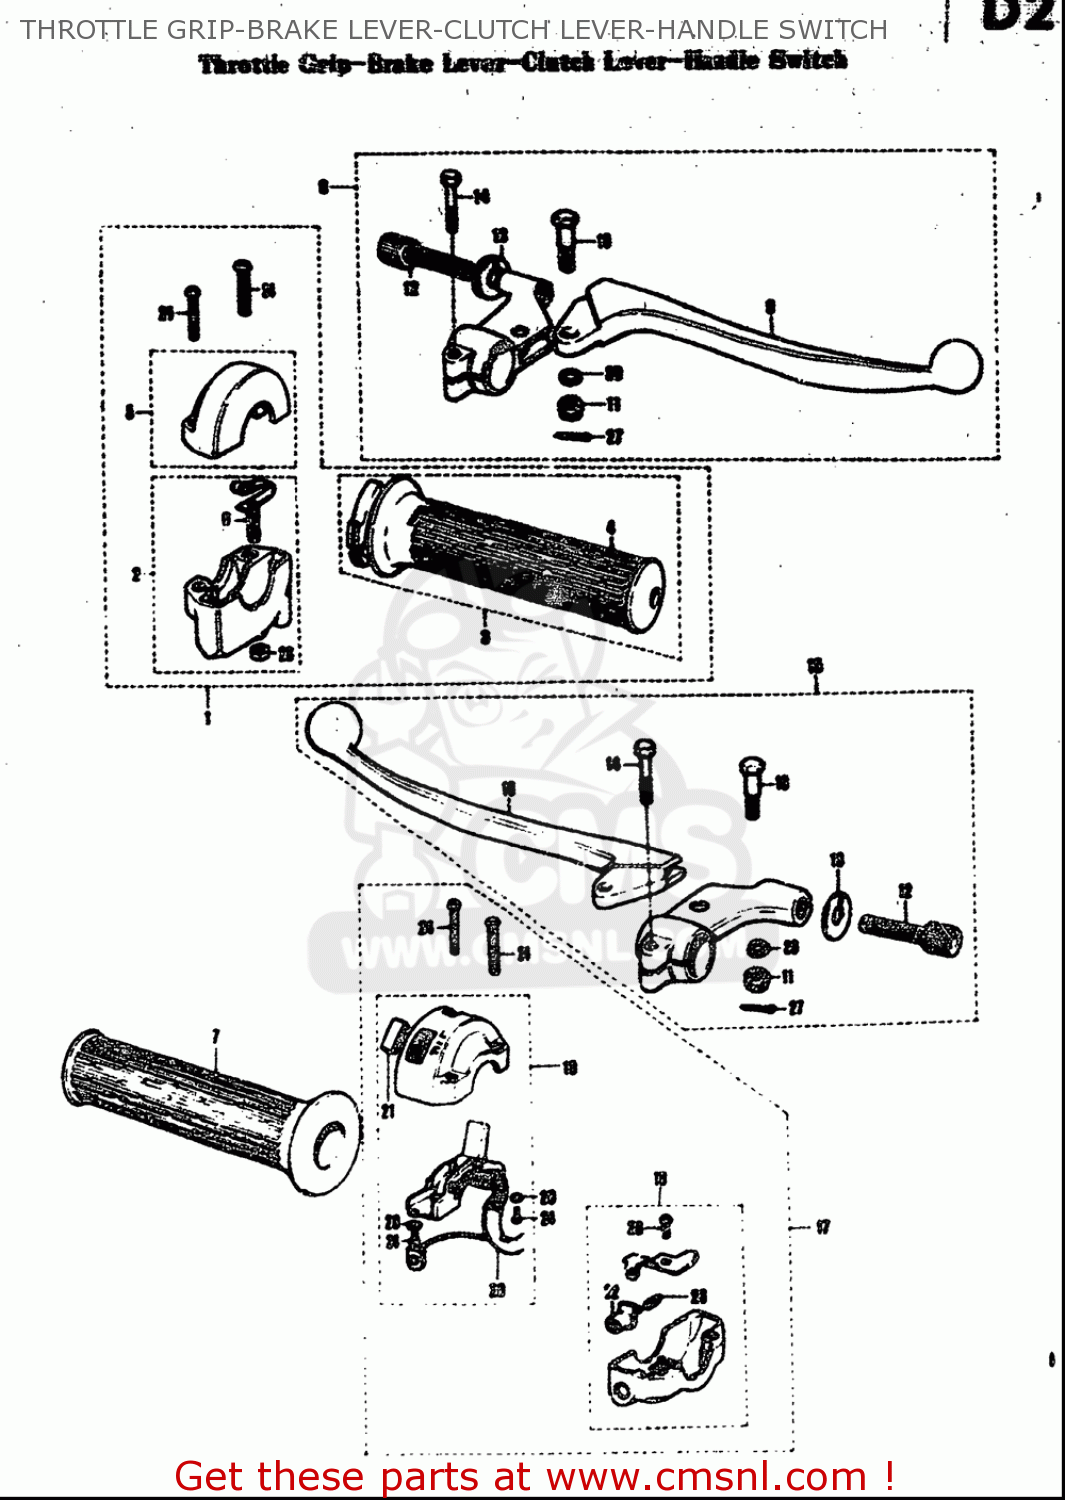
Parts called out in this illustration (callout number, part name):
6	ADJUSTER, THROTTLE
7	GRIP
10	BOLT,LEVER PIVOT
11	NUT,LEVER FITTNG
12	ADJUSTER,CABLE
13	NUT,CABLE ADJUSTER
14	BOLT
22	BUTTON, HORN
26	SCREW
27	PIN 16X20
28	NUT
29	WASHER,LOCK
30	WASHER,LOCK
